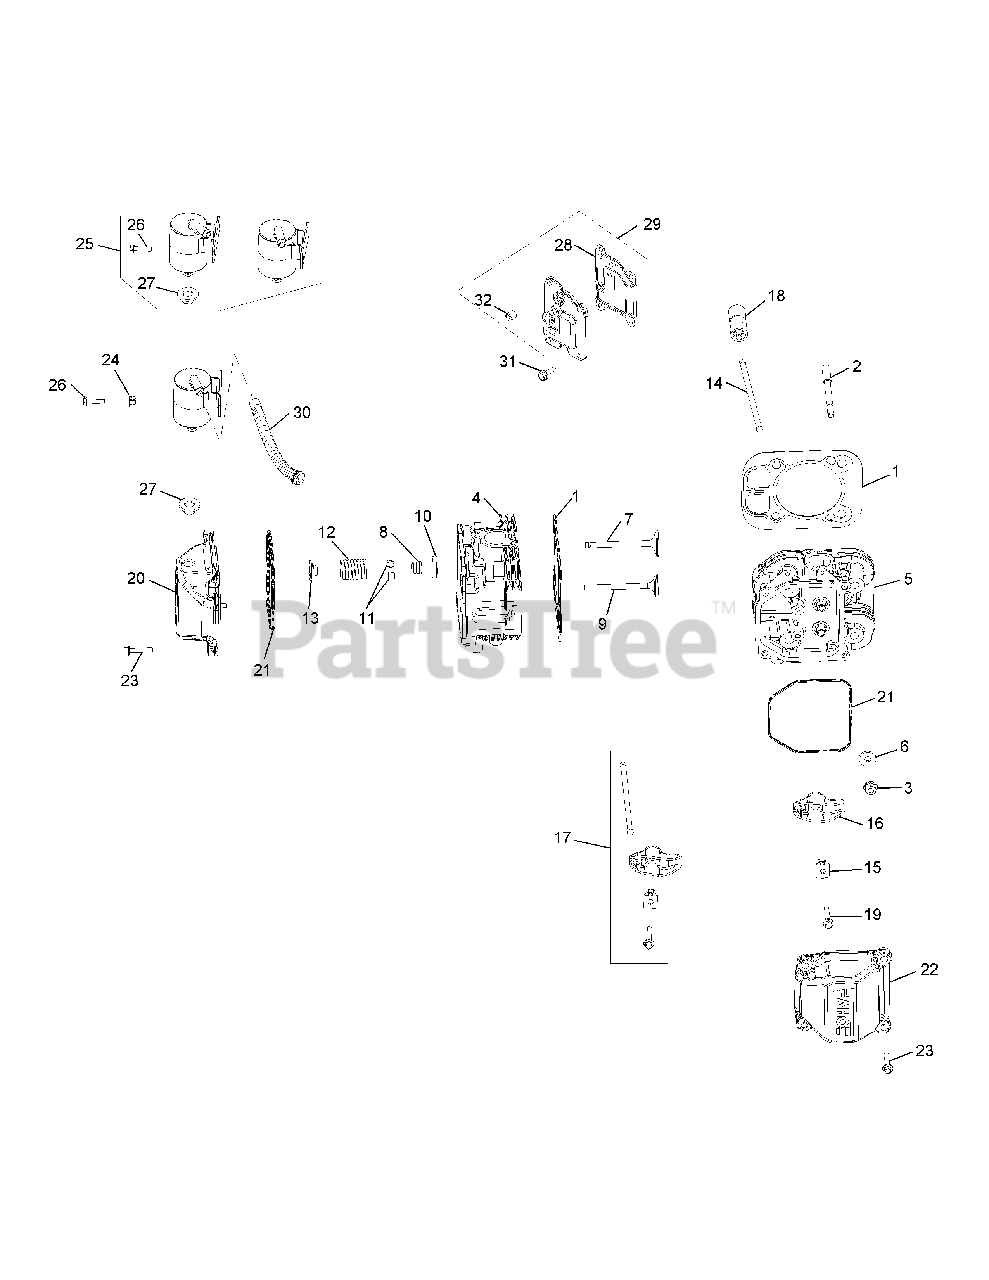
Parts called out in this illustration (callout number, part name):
1	Cylinder Head Gasket Kit
2	Stud, M8 x 1.25
3	Flange Nut, M8 x 1.25
4	#1 Cylinder Head Assembly Kit
5	#2 Cylinder Head Assembly Kit
6	Flat Washer, 8.6 mm
7	Intake Valve (STD)
7	Intake Valve (.25)
8	Valve Band Seal
9	Exhaust Valve (STD)
9	Exhaust Valve (.25)
10	Spring Retainer
11	Retainer Kit
12	Valve Spring
13	Valve Spring Cap
15	Rocker Arm Pivot
17	Valve Train Kit
18	Hydraulic Valve Lifter Kit
19	Flange Screw, M6 x 1.0 x 34
20	Valve Cover Kit
21	Valve Cover O-Ring
22	Plain Rocker Cover Kit
23	Flange Screw, M6 x 1.0 x 30
25	Breather Separator Kit (Inc. 26-27)
26	Hi-Lo Hex Flange Screw
27	Rubber Grommet
28	Breather Gasket
29	Breather Cover Kit w/ Gskt. (Inc. 28 & 33)
31	Flange Screw, M6 x 1.0 x 20
32	Pipe Plug, 1/8
